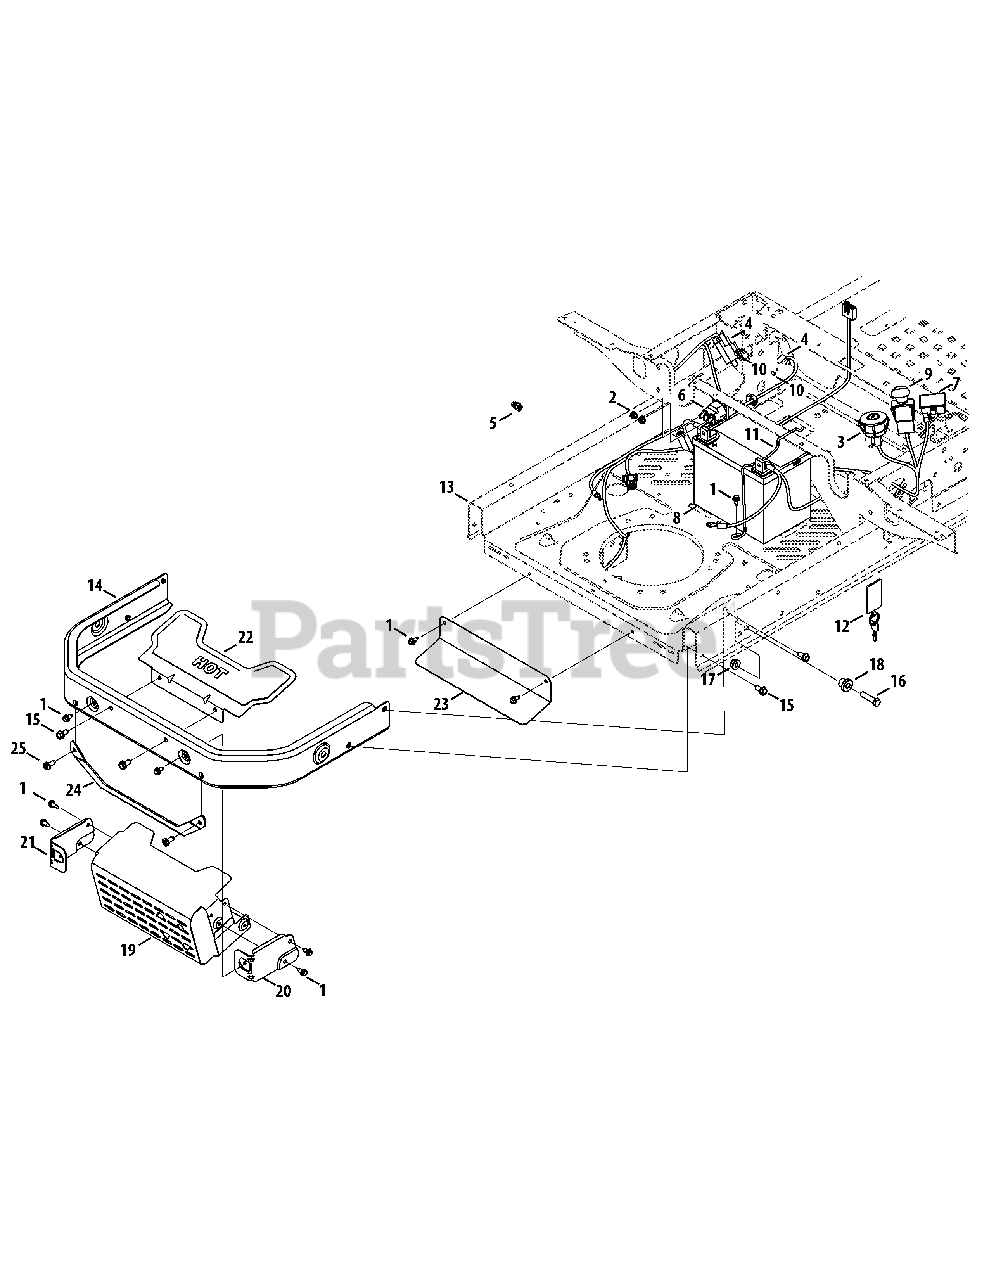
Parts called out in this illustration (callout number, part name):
1	Hex Washer Screw, 1/4-20 x .625
2	Flange Lock Nut, 1/4-20
3	Key Switch
4	Interlock Switch
5	Harness
6	Solenoid
7	Hour Meter/Service Minder
8	Battery
9	PTO Switch
10	Shoulder Screw
11	Battery Retainer
12	Key
13	Frame
15	Hex Washer Screw, 5/16-18 x .750
16	Hex Screw, 3/8-16 x 1.25
17	Flange Lock Nut, 3/8-16
18	Shoulder Spacer, .38 x 1.0 x .70
19	Muffler Shield Assembly
20	RH Muffler Shield Mount Bracket
21	LH Muffler Shield Mount Bracket
22	Muffler Shield
23	Lower Heat Shield
24	Rear Muffler Shield Bracket
25	Screw, Self-Tapping, 5/16-18, 0.750
